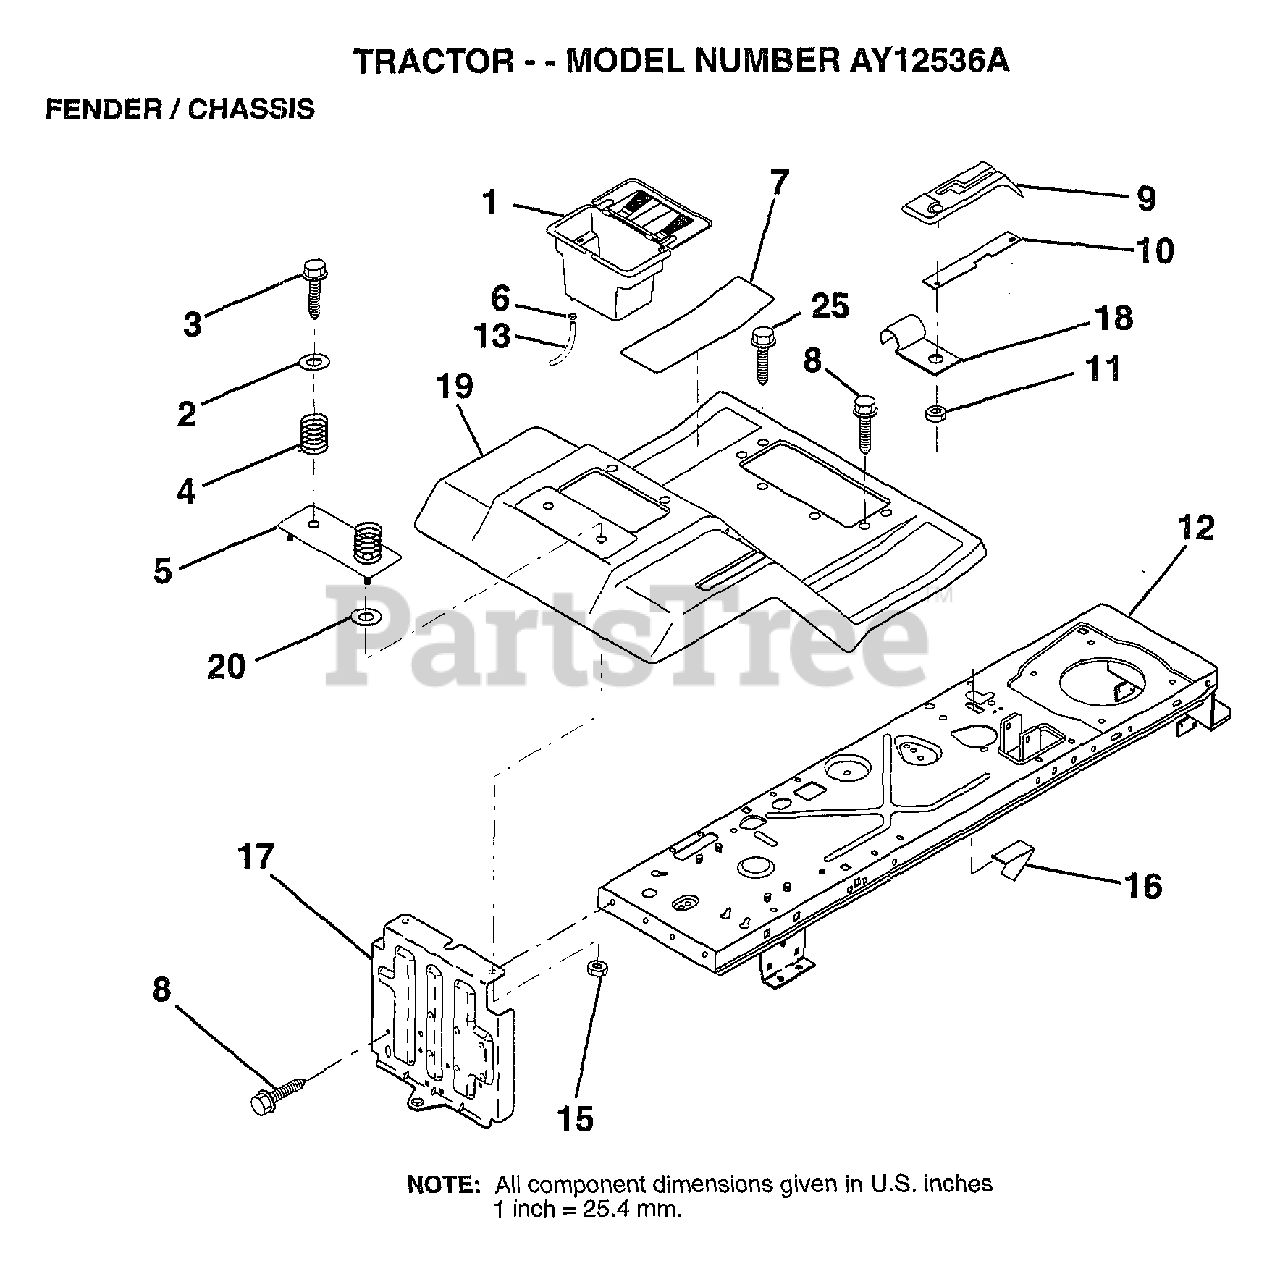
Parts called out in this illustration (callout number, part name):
2	WASHER
3	SCREW
4	SPRING COMPRESSIO
5	PLATE.FEND.LR.ASM
6	HOSE CLAMP T
7	PAD FOOTREST
8	SCREW
9	CONSOLE SHFT 5SP
10	PLATE LOCK SHIFT
11	NUT
12	CHASSIS.WELD.ASM.
13	TUBE T
15	NUT HXKEP 1/4X20
17	DRAWBAR ASM LR
18	"CLIP,INSULATOR"
19	FENDER/FOOTREST
25	SCREW
